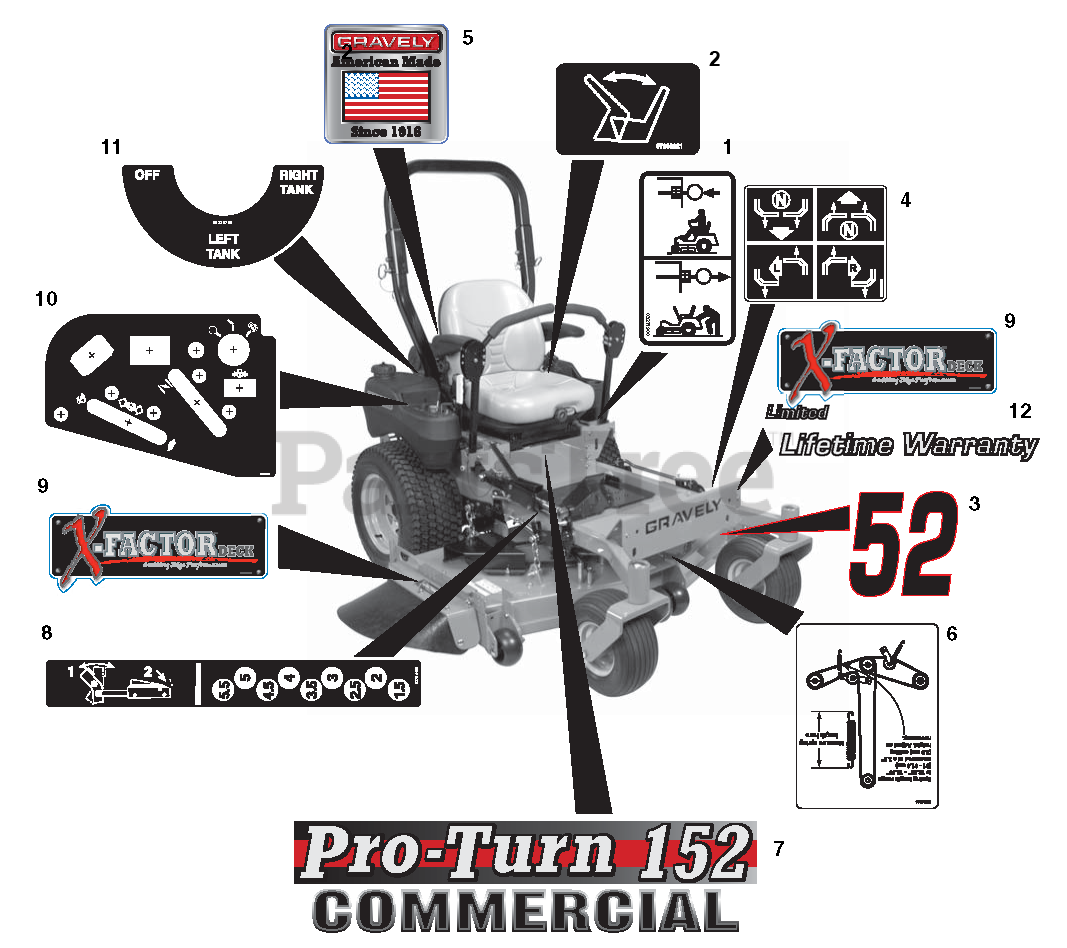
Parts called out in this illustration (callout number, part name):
1	DECAL, TRANSMISSION DISCONNECT
2	DECAL - SEAT RELEASE
3	DECAL, 48"
3	DECAL, "52" (PROZOOM DECK)
3	DECAL, 60"
4	DECAL, INSTRUCTIONAL-STEERING
5	DECAL, MADE IN AMERICA GRAVELY
6	DECAL, BELT ROUTING
7	DECAL, PRO-TURN 148
7	DECAL, PRO-TURN 152
7	DECAL, PRO TURN 160
8	DECAL, HEIGHT OF CUT
9	DECAL, X-FACTOR DECK
10	DECAL, CONTROL PANEL
11	DECAL, FUEL VALVE
12	DECAL, LIMITED LIFETIME WARR
